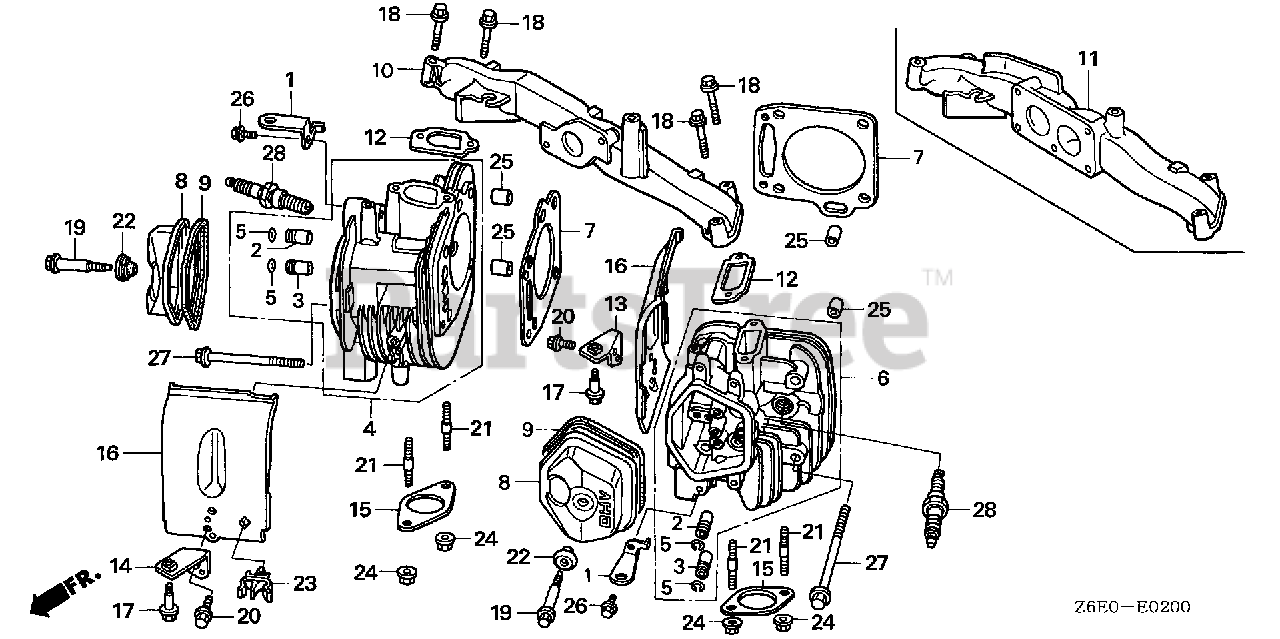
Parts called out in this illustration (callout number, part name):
1	HANGER, ENGINE
2	GUIDE, VALVE (OVER SIZE)
3	GUIDE, EX. VALVE (OVER SIZE)
4	CYLINDER HEAD (#1)
5	CLIP, VALVE GUIDE
6	CYLINDER HEAD (#2)
7	GASKET, CYLINDER HEAD
8	COVER, HEAD
9	GASKET, HEAD COVER
10	MANIFOLD, IN.
12	GASKET, IN. MANIFOLD
13	BRACKET, R. AIR CLEANER
14	BRACKET, L. AIR CLEANER
15	GASKET, EX. PIPE
16	SHROUD, HEAD
17	BOLT, FLANGE (6MM)
18	BOLT, SOCKET (8X45)
19	BOLT, HEAD COVER
20	BOLT, FLANGE (6X14) (CT200)
21	BOLT, STUD (8X22)
22	WASHER, HEAD COVER
23	CLIP, FUEL TUBE
24	NUT, FLANGE (8MM)
25	PIN, DOWEL (12X20)
26	BOLT, FLANGE (8X20)
27	BOLT, FLANGE (10X80)
28	SPARK PLUG (BPR2ES) (NGK)
28	SPARK PLUG (J14CR-U) (DENSO)
28	SPARK PLUG (ZGR4A)
28	SPARK PLUG (J16CR-U) (DENSO)
28	SPARK PLUG (ZGR5A)
